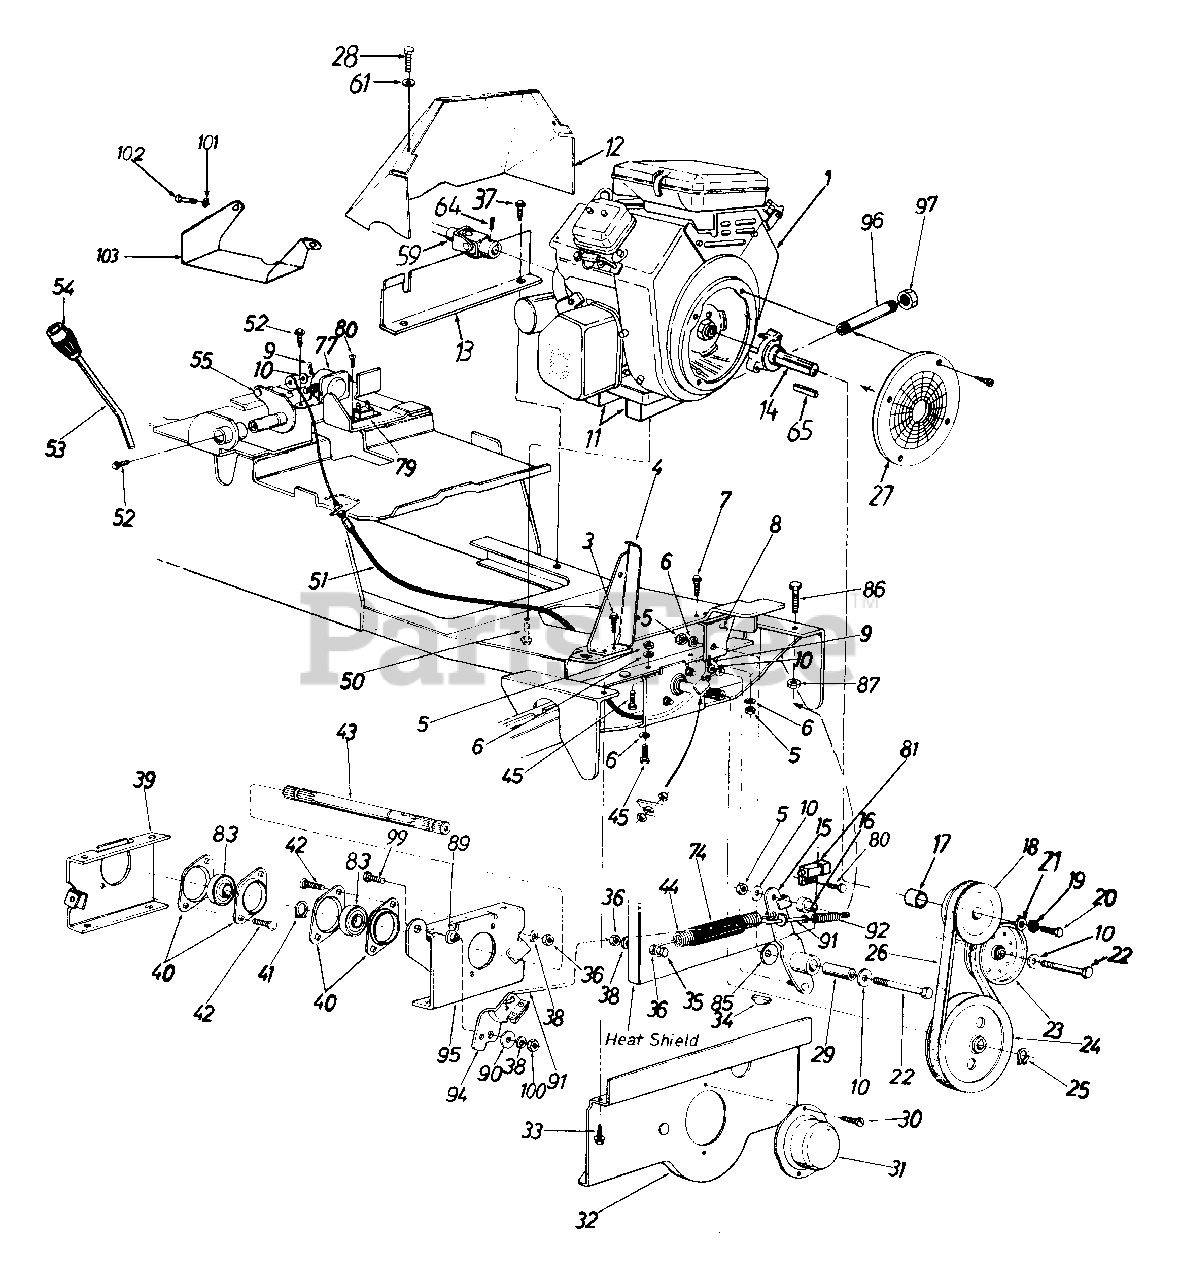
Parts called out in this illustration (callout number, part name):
1	Engine
3	Hex Wash. Hd. Self-Tap Scr. 1/4-20 x .75" Lg.
6	L-Wash. 3/8" I.D.
7	Hex Wash. Hd. Self-Tap Scr. 5/16-18 x .75" Lg.
10	Fl-Wash. .38" I.D. x 1.25" O.D. x .100" Thk.
11	Engine Spacer Bar
14	Crankshaft Ext.
15	PTO Idler Ass'y.
16	Idler Adapter
17	Pulley Spacer
18	Engine PTO - Pulley
19	L-Wash. 3/8" I.D.
20	Hex Bolt 3/8-24 x .88" Lg.
21	Fl-Wash. 3/8" I.D. x 1.37" O.D.
22	Hex Bolt 3/8-16 x 2.50" Lg.
23	Flat Idler Pulley
24	1/2" V-Pulley 7.00" O.D. (PTO)
25	Snap Ring
26	V-Belt (PTO)
27	Engine Screen
28	Hex Bolt M6-1.0 x 10 MM Lg.
29	Spacer .375" I.D. x .62" 0 D. x 1.830" Lg.
30	Hex "B" Tap Scr. #10 x .50" Lg.
31	PTO Cup
34	#91 Hi-Pro Key
35	Hex Bolt 5/16-18 x 1.25" Lg.
36	Hex Nut 5/16-18 Thd.
37	Hex Wash. Hd. Tap Scr. 5/16-18 x .5" Lg.
38	L-Wash. 5/16" I.D.
39	PTO Brg. Retainer Brkt.
40	1.00" Dia. Brg. w/Flangette
41	Snap Ring
42	Carr. Bolt 5/16-18 x .75" Lg.
43	Spline Shaft
44	Extension Spring (PTO Clutch)
45	Hex Scr. 3/8-16 x 1.00" Lg.
50	Hex L-Wash. TT-Tap Scr. 3/8-16 Thd.
51	PTO Control Cable
52	Hex Wash. Hd. TT-Tap Scr. 1/4-20 x .5" Lg.
53	PTO Handle
54	Shift Knob
55	PTO Actuator Lever Ass'y.
59	Universal Drive Shaft Comp.
61	Fl-Wash. .281" I.D. x .5" O.D.
64	Set Scr. 5/16-18 x .38" Lg.
65	Sq. Key 1/4" x 2.00" Lg.
74	Spring Cover Tubing (PTO Clutch)
77	Solenoid
79	Circuit Breaker
80	Truss Mach. Scr. #10 x .50" Lg.
81	Safety Switch (PTO)
83	Ball Bearing
85	Bell-Wash. .39" I.D. x 1.13"
86	Hex Bolt 3/8-16 x 1.5" Lg.
87	Hex Cent. L-Nut 3/8-16 Thd.
89	Shoulder Spacer
90	Fl-Wash. .33" I.D. x 1.25" O.D.
91	PTO Brake Rod
92	Extension Spring 2.15" Lg.
94	Brake Ass'y.
95	PTO Brg. Retainer Brkt. Ass'y.
96	Pipe Nipple 3/8" x 5" Lg.
97	Oil Drain Cap
99	Hex Bolt 5/16-24 x .75" Lg.
100	Hex Nut 5/16-24 Thd.
101	L-Wash. 7/16" I.D.
102	Hex Bolt 7/16-14 x .75" Lg.
103	Heat Shield
